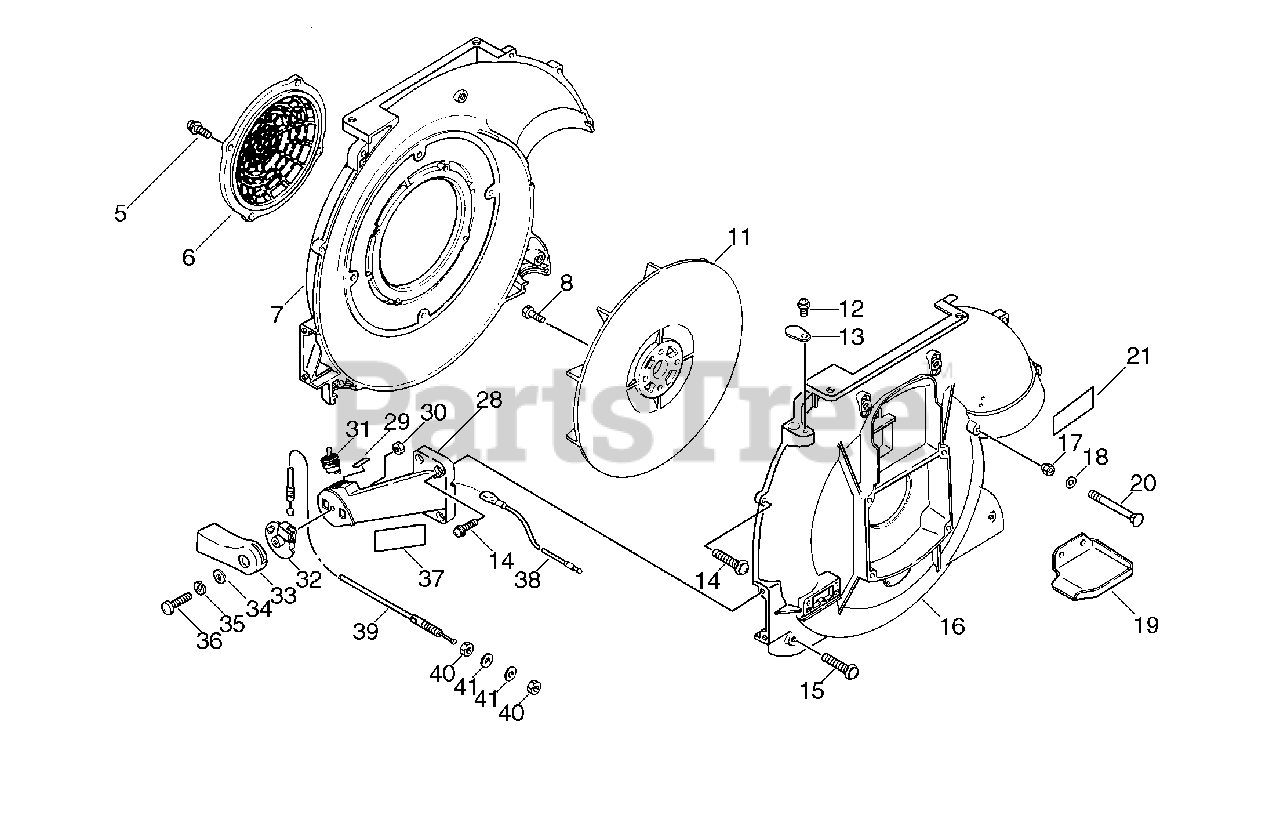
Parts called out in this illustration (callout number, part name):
6	SHIELD, DEBRIS
7	COVER, FAN - INNER -- ORANGE
12	SCREW 5×10
14	SCREW 5×20
15	SCREW 5×25
16	COVER, FAN - OUTER
17	NUT - 5 -- CAP
18	WASHER, FLAT 5.5×10×0.8
19	BRACKET, MUFFLER COVER
21	LABEL, NOISE
28	MOUNT, THROTTLE LEVER
29	LABEL, ON-OFF
30	NUT, HEX M6
31	IGNITION SWITCH ASSY
33	CONTROL, THROTTLE
35	WASHER, SPRING 6
36	SCREW 6×25
37	LABEL - CAUTION
39	CABLE, THROTTLE
41	WASHER 6.5×13×1
